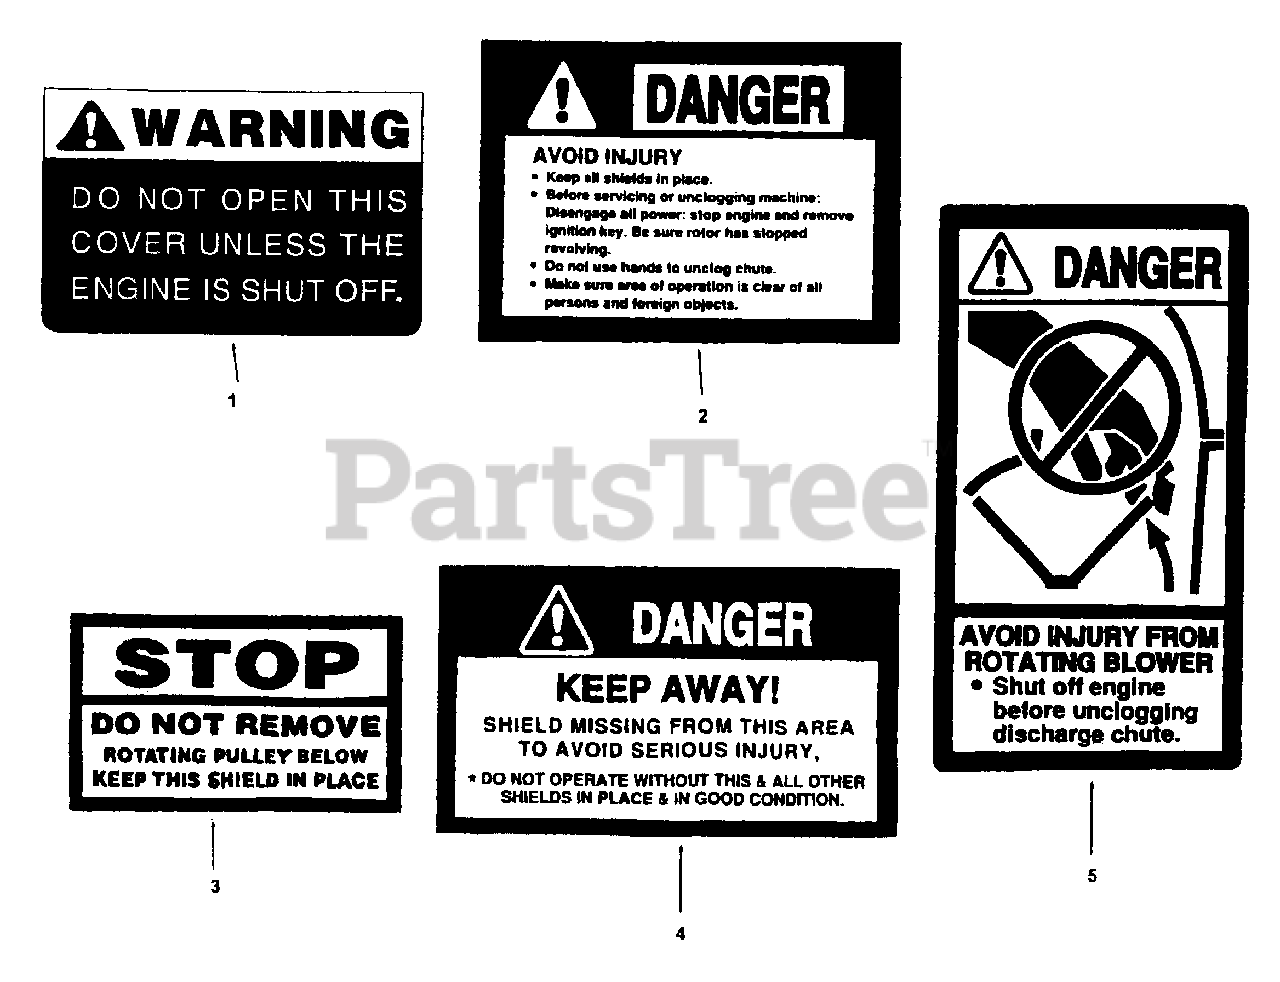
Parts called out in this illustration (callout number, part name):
1	Bagger Cover Decal
2	Top of Belt Shield Decal
3	Don't Remove Decal
4	Danger Shield Missing Decal
5	Danger Implr. Decal
